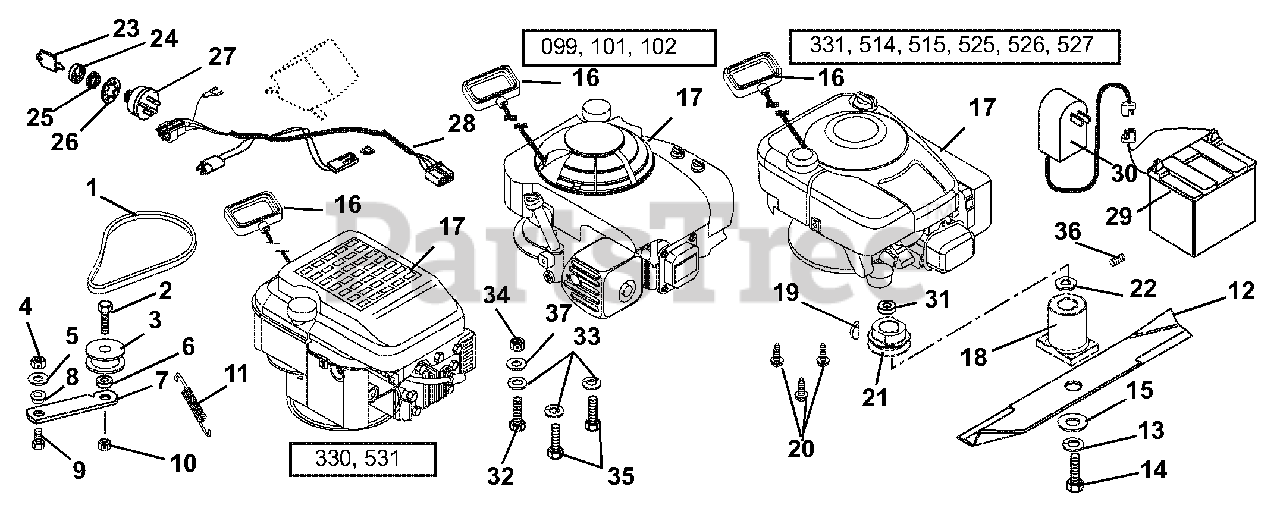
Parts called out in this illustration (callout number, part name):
1	V-BELT, 3L-COGGED
2	@BLT-HEX .44-14X1.50 GR5 YWZC
3	IDLER-FLAT 1.75 X .47
4	@NUT-LK-CTR .31-18 YWZC
5	@WSHR-FL-STL.344X.688X.065YWZC
6	BSHG-SLV .469 X .750 X .430
7	IDLER ARM
8	BSHG-FLG .325X.501X.250X1.120
9	@BLT-HEX .31-18X.75 GR5 YWZC
10	@NUT-LK-CTR .44-14 YWZC
11	SG-TENS .043X.44X3.31 WLD 5.8
12	BLADE, 21" LM MULCHING
12	21" MOWER BLADE
12	BLADE, 21" MOWER TUNGSTEN
13	@WSHR-LK .38X.094 REG YWZC
14	BLT-HEX .38-24 X 2.00 GR8 YWZC
15	WSHR-FL-STL .390X1.5X.125 YWZC
16	HANDLE, RECOIL START
17	ENGINE, B&S QUANTUM 6.5HP
17	ENGINE, B&S INTEK PRO 6.75
17	ENG, B&S 6.75HP INTEK OHV RCL
17	ENG, B&S 6.75HP INTEK OHV ELEC
17	ENGINE, HONDA GCV
17	ENGINE - HONDA 5.5 HP OHV
18	ADAPTER-SINTERED IRON LM
18	ADAPTER - BLADE HUB
19	KEY-WDRF .156X.625X.25 SAE 6
20	@SCR-TAP .38-16X1.00 HWH TR YZ
21	PULLEY-SINTERED IRON LM
21	PULLEY - UNV DRIVE - STEEL
22	WASHER-WAVE .885X1.311X.125
23	KEY -W/CAP
24	CAP - IGNITION SWITCH
25	NUT-PANEL .625-32 GRECO
26	WSHR-LK-INT .625X.045 YWZC
27	SWITCH, KEY ELECTRIC START-LM
28	HARNESS, WIRE
29	BATTERY,
30	BATTERY CHARGER
30	CHARGER, 220 V BATTERY
31	SPACER, .875X1.125X.551
32	BLT-HEX .31-24X1.50 GR5 YWZC
33	@WSHR-LK .31X.078 REG YWZC
34	NUT-HEX .312-24 YWZC
35	BLT-HEX .31-24X1.00 GR5 YWZC
36	SCR-SET .31-18X.38 SKHCUPDL
37	@WSHR-FL-STL.344X.688X.065YWZC
